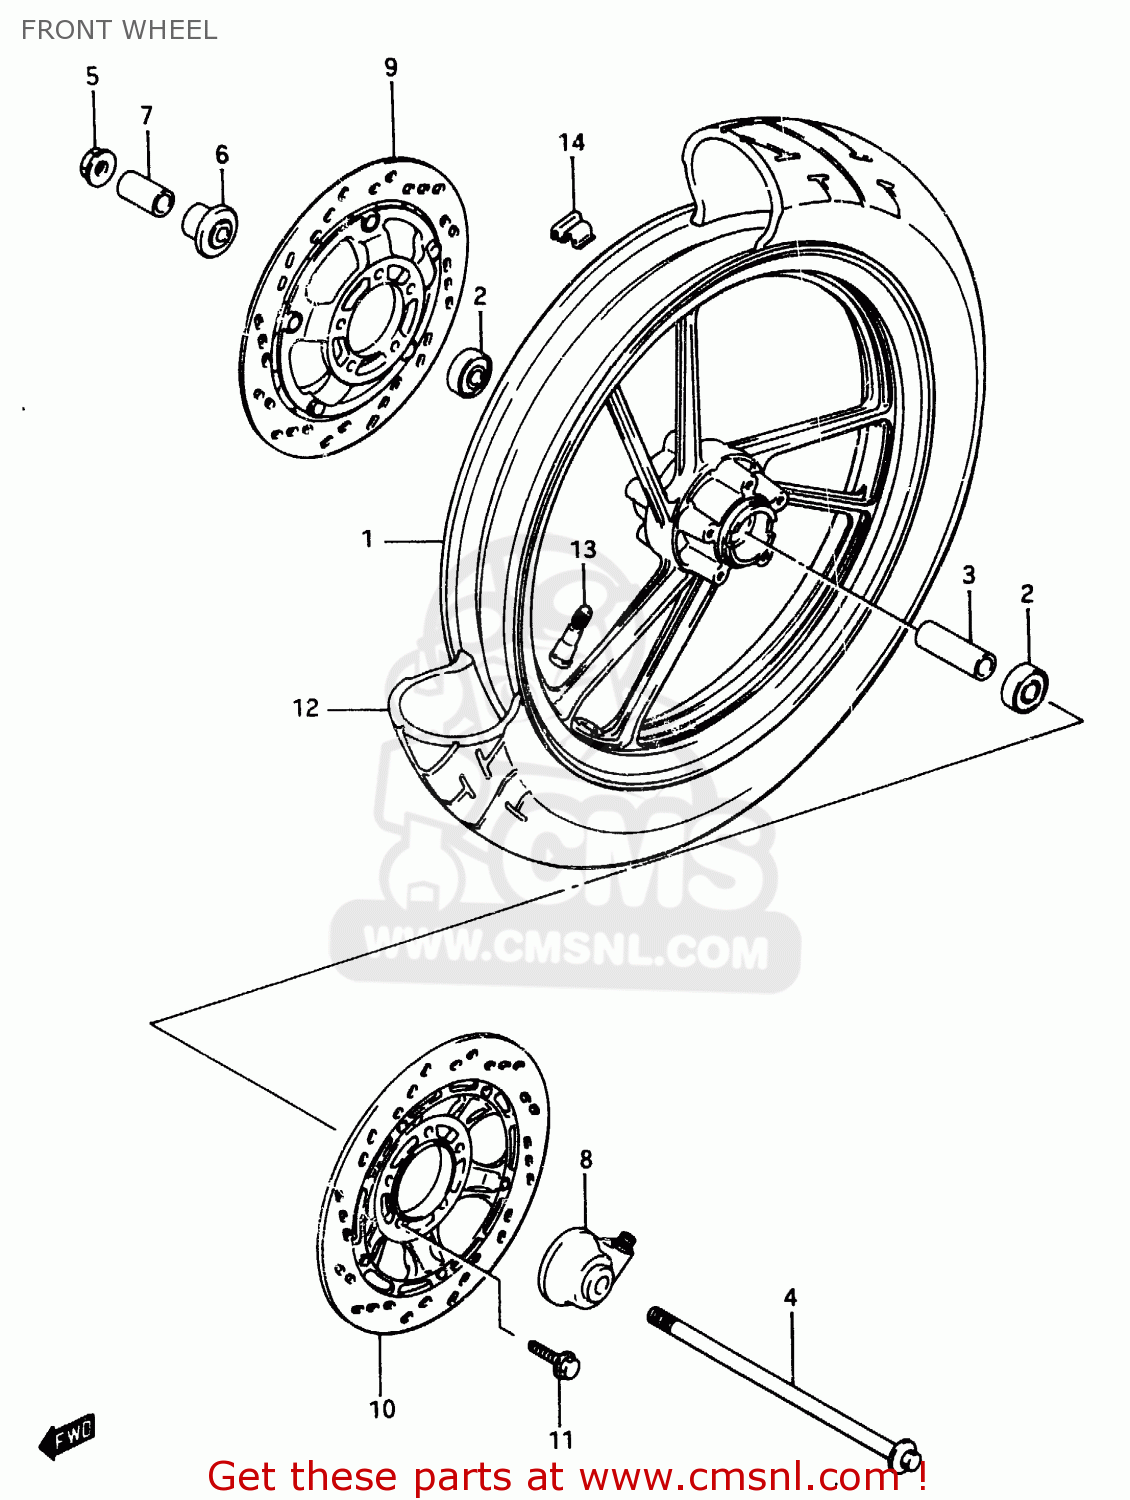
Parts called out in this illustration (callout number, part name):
1	WHEEL, FRONT (MT2.15X16) WHITE
2	BEARING
3	SPACER
4	AXLE, FRONT
5	NUT 12MM
6	SPACER,FRONT AXLE,RIGHT
7	SPACER
8	BOX ASSY,SPEEDOMETER GEAR
9	DISC,FR BRAKE,R
10	DISC, FRONT BRAKE LH
11	BOLT
12	TIRE, T/L FRONT (100/90H16)
13	VALVE,TIRE
14	BALANCER,WHEEL(10G)
